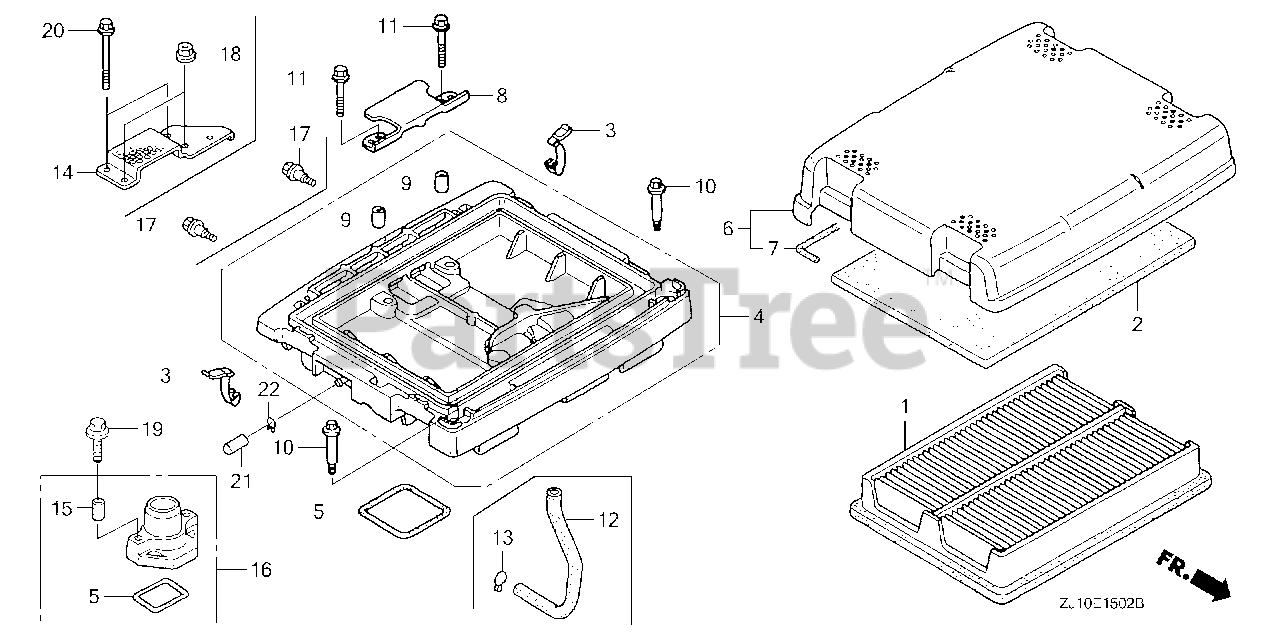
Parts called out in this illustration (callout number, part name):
1	ELEMENT, AIR CLEANER
2	FILTER (OUTER)
3	CLIP, AIR CLEANER
4	HOUSING, AIR CLEANER
5	SEAL, AIR CLEANER HOUSING
6	COVER ASSY., AIR CLEANER
7	SEAL, AIR CLEANER COVER
8	PLATE, AIR CLEANER SETTING
9	COLLAR A, AIR CLEANER
10	BOLT, SPECIAL (5MM)
11	BOLT, FLANGE (6X28)
